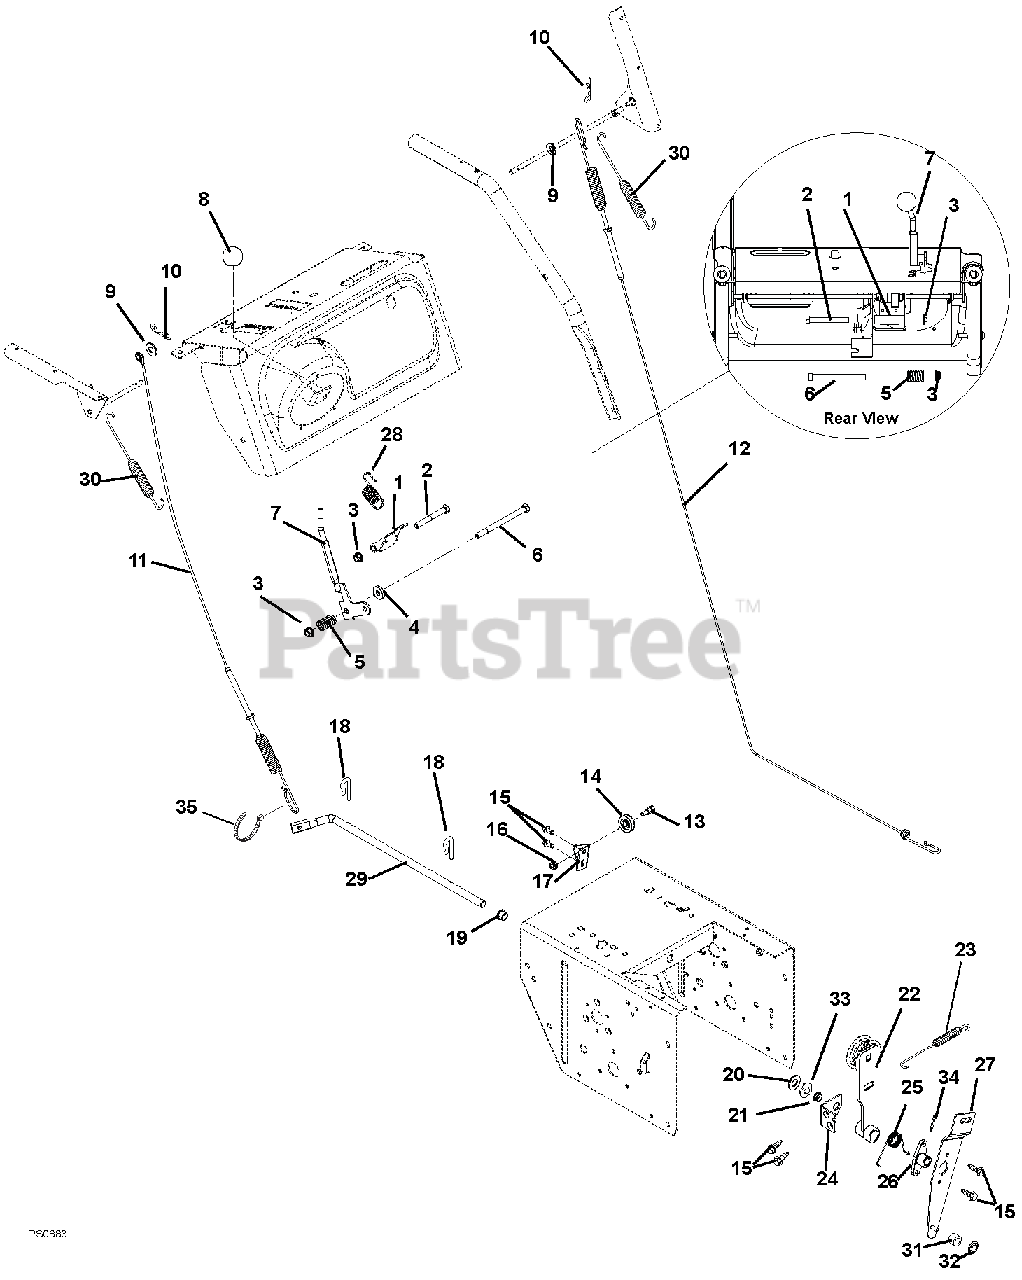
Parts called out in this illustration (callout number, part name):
1	ARM, INTERLOCK
2	@BLT-HEX .38-16X3.00 GR5 YWZC
3	@NUT-LK-TOP-FLG .38-16 YWZC
4	WSHR-FL-STL .406X1.00X.188 YWZ
5	SG-COMP .125X.781X1.250
6	@BLT-HEX .38-16X5.00 GR5 YWZC
7	LEVER, SHIFT
8	KNOB,BALL -BLACK 1.47" .375-16
9	@WSHR-FL-STL.281X.62X.065 YWZC
10	PIN-HAIR INT .06X.18X.77
11	CABLE, ATTACHMENT
12	CABLE, TRACTION
13	BOLT, SHLDR-.375X.375X.25-20
14	PULLEY, CABLE
15	@SCR-TAP .25-20X.50 HWH TR YWZ
16	@NUT-LK-TOP-FLG .25-20 YWZC
17	BRACKET, CABLE PULLEY
18	CLIP, SPRING
19	BUSHING, POLYLINER-.50 SPLIT
20	@WSHR-FL-STL.531X1.06X.095YWZC
21	BUSHING, POLYLINER-.50 SNAPIN
22	ARM, IDLER-TRACTION
23	SG-TENS .06X.482X5.35
24	BRACKET, SUPPORT
25	SG-TORS .067X.88
26	HUB, BRAKE ARM
27	ARM, IDLER-ATTACHMENT
28	SPRING-EXT .047X.438X1.45
29	ARM, ATTACHMENT
30	SG-TENS .056X.60X4.40
31	BSHG,SLV .270 X .750 X .250
32	RG-RTNG-EXT .250X.010
33	WAVE WASHER .531X.781X.125FH
34	PIN-ROLL .125X1.00
35	CABLE TIE LG 5-1/2
